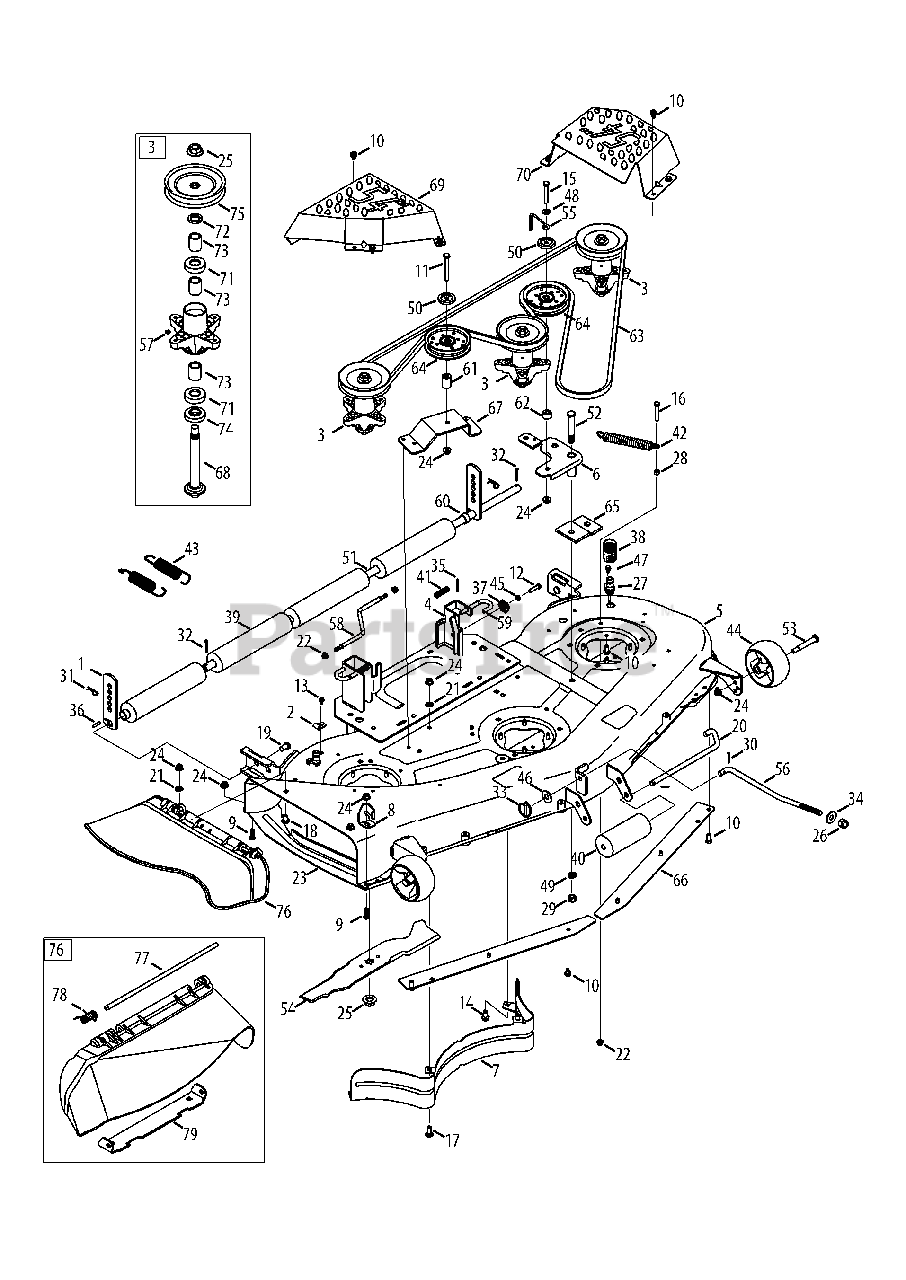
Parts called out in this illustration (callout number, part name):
1	Height Adjust Bracket
2	Retainer Hook Bracket
3	Spindle Assembly
4	Deck Hanger Bracket Assembly
5	Deck Assembly
6	Idler Assembly
7	Inner Baffle
8	Deflector Chute Stop
9	Hex Screw, 3/8-16:1.00
10	Taptite Screw, 5/16-18:.750
11	Hex Screw, 3/8-16:3.00
12	Hex Screw, 5/16-18:1.25
13	Hex Screw, 1/4-20 x .500
14	Taptite Screw, 3/8-16:0.750
15	Hex Screw, 3/8-16:2.50
16	Hex Screw, 5/16-18:2.00
17	Carriage Bolt, 3/8-16:1.00
18	Carriage Bolt, 3/8-16:0.75
19	Clevis Pin, .50 DIA x .78 LG
20	Roller Pin, 1/2 DIA x 7.31 LG
21	Push Nut, 3/8
22	Flangelock Nut, 5/16-18
23	Finger Guard
24	Flangelock Nut, 3/8-16
25	Flange Nut, 5/8-18
26	Flexlock Nut, 1/2-13
27	Deck Wash Nozzle
28	Hex Nut, 5/16-18
29	Hexlock Nut, Counterlock, 1/2-13
30	Cotter Pin, 3/32:1.0
31	Click Pin, .092 x 1.64 LG
32	Cotter Pin, 5/32:1.25
33	Lynch Pin, .1875
34	Washer, .630 x 1.25 x .180
35	Cotter Pin, 1/8 x 1.25
36	Spring Pin, 1/4 DIA x 1.00 LG
37	Deck Gear
38	Water Nozzle Adaptor
39	Deck Roller
40	Front Roller
41	Compression Spring, .535 OD x 1.751 LG
42	Extension Spring, .85 OD x 5.915 LG
43	Extension Spring, 1.15 OD x 5.99 LG
44	Deck Wheel
45	Lock Washer, 5/16
46	Flat Washer, .531 x 1.25 x .100
47	Shoulder Screw, 1/4-20 x 0.50
48	Flat Washer, .406 x .875 x .059
49	Lock Washer, 1/2
50	Pulley Cap
51	Shaft, .750 x .47.12
52	Shield Screw, .625 x 2.50:1/2-13
53	Shoulder Bolt, .496 x 2.50:3/8-16
55	Belt Keeper Rod
56	Deck Lift Rod
57	Lube Fitting
58	Deck Sway Rod
59	Deck Release Handle Rod
60	Spacer, .82 ID x 1.00 OD x .53
61	Spacer, .380 x .900 x 1.313
62	Spacer, .385 ID x .88 x .64
63	V Belt
64	Idler Pulley, 4.25"DIA
65	Pulley Stabilizer Bracket
66	Deck Skirt
67	Stationary Idler Bracket
68	Spindle Shaft, 6.95 LG
69	RH Spindle Cover
70	LH Spindle Cover
71	Ball Bearing, .787 ID x 1.85 OD x .551
72	Spacer, .790 ID x 1.25 OD x .175
73	Spacer, .80 x 1.10 x 1.322 LG
74	Spacer, .79 x 1.82 x .55 LG
75	Deck Pulley
76	Chute Assembly
77	Hinge Pin
78	Torsion Spring, .44 ID x 2.0
79	Chute Bracket
